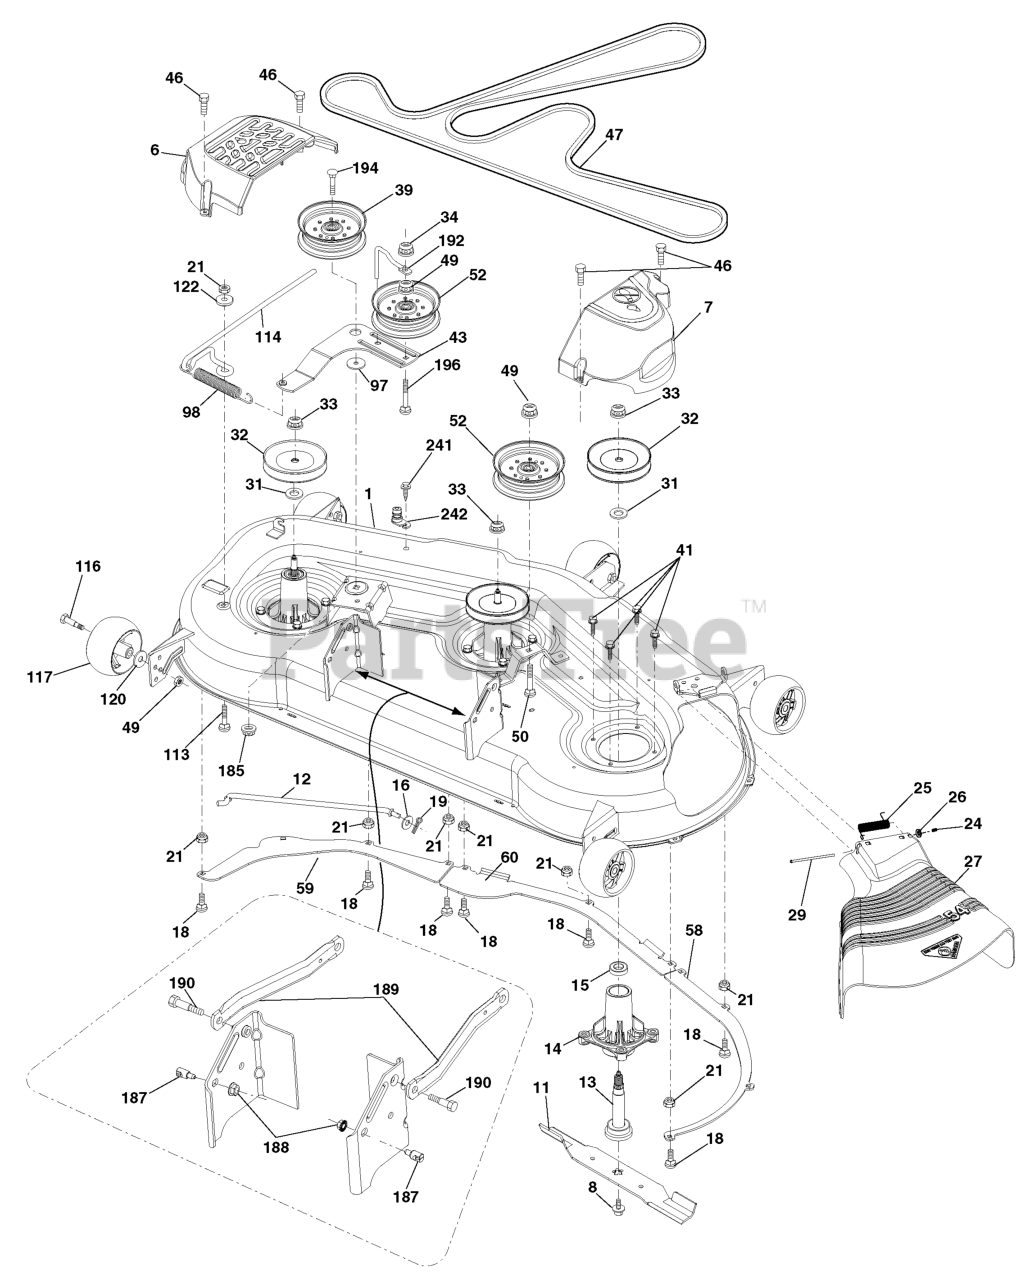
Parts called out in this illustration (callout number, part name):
1	Deck Weldment Mower
6	Cover Mandrel LH
7	Cover Mandrel RH
8	Bolt 7/16 Asm. Blade
11	Blade Bagging
12	Rod Anti-Sway
13	Shaft Asm. w/Lower Bearing
14	Housing, Mandrel
15	Bearing, Ball, Mandrel
16	Washer 13/23 x 13/16 x 1 2 Ga.
18	Bolt RdHd. 5/16-18 unc x 5/8
19	Pin Cotter 5/16 Bowtie Lock
21	Nut, Crownlock 5/16-18 unc
24	Cap Sleeve
25	Spring, Torsion
26	Nut, Push
27	Deflector Shield
29	Rod, Hinge
31	Washer, Spacer Mower Vented
32	Pulley, Mandrel
33	Nut, Flg. Top Lock
34	Nut Crownlock 3/8-16 unc
39	Pulley, Idler
41	Bolt Hex Wshr
43	Arm, Idler
46	Screw, Thdrol. 1/4-20 x 5/8
47	Belt Drive Deck
49	Nut, Lock Flg. 3/8-16 unc
50	Bolt Rdhd. Sqnk. 3/8-16 unc x 2
52	Pulley Idler
58	Baffle Right
59	Baffle Left
60	Baffle Center
97	Washer Hardened
98	Spring Drive
113	Bolt Rdhd. Sqnk. 5/16-18 x 3/4
114	Rod Tension Relief
116	Bolt, Shoulder
117	Gauge Wheel
120	Washer 13/32 x 1-1/4 x 12 Ga.
122	Bushing Tension Relief
184	Nut Lock Hex Flange 5/16-18
185	Nut Lock Flange 7/16-14 Gr. 5
187	Stud Fastener w/"D" Anti-Rotation
189	Arm Susp. Mower Rear
190	Bolt Shoulder
192	Keeper Belt Idler
194	Bolt Carr. Sqnk. 7/16-24 x 2
196	Bolt Rdhd 3/8-16 x 2-1/2 Gr. 5
241	Screw
242	Port Washout
